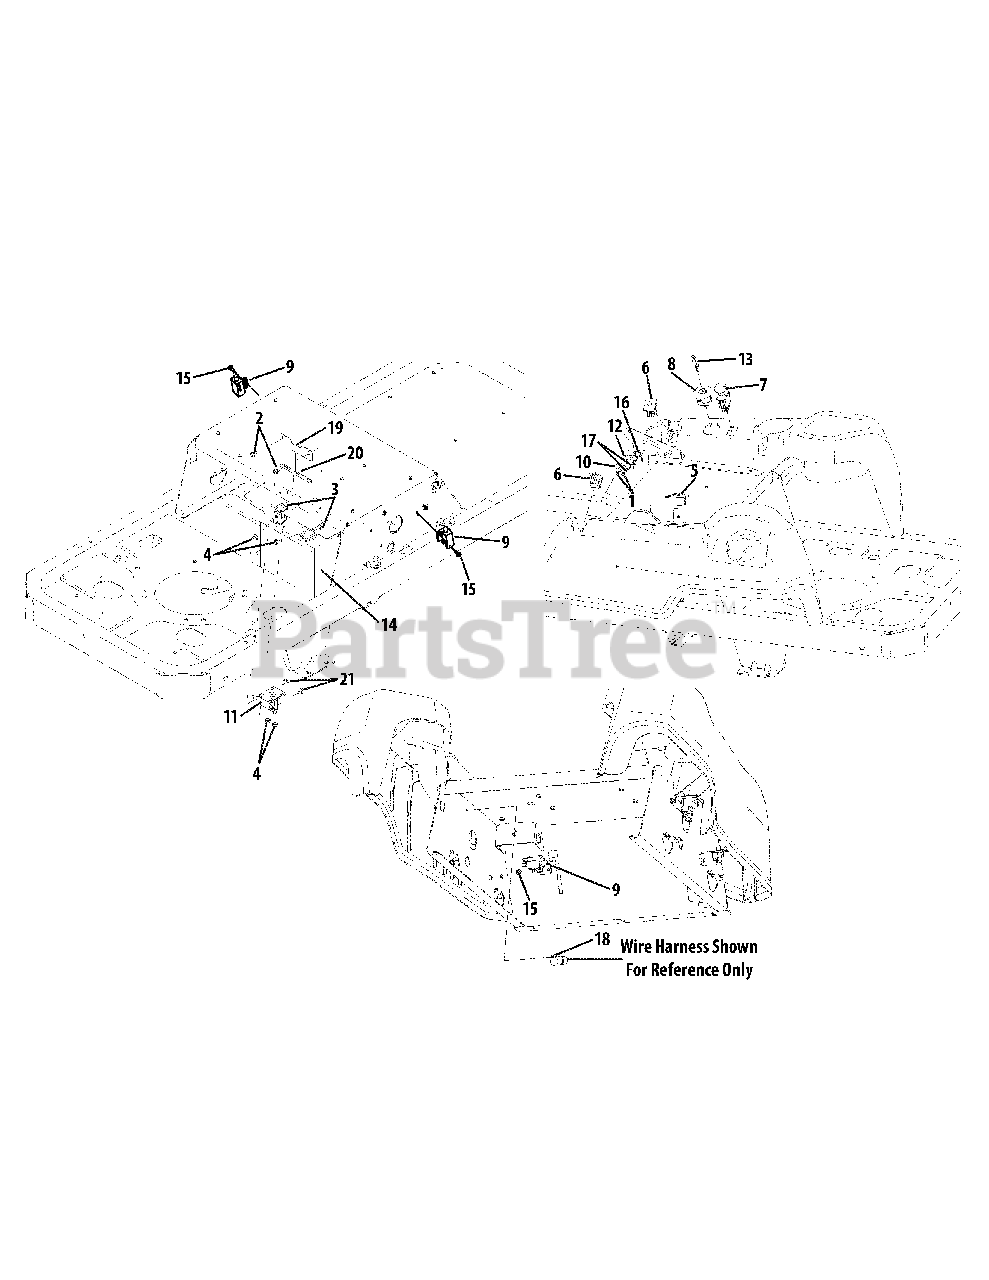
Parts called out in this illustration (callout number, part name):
1	Hex Screw, #8-18 x .5
2	Hex Screw, 1/4-20 x .5
3	Hex Screw, 1/4-20 x .75
4	Hex Nut, 1/4-20
5	Hour Meter
6	Double Pole Neutral Switch
7	PTO Switch
8	Ignition Switch
9	Interlock Switch
10	Outer Seat Swing Switch
11	Solenoid
12	Inner Seat Spring Switch
13	Key
14	Battery, 235 CCA
15	Shoulder Screw, #10-32 x .500
16	Insulator Boss Plate
17	Insulator Plate
18	Cable Tie
20	Trim Strip
21	Hex Screw, 1/4-20 x .375
